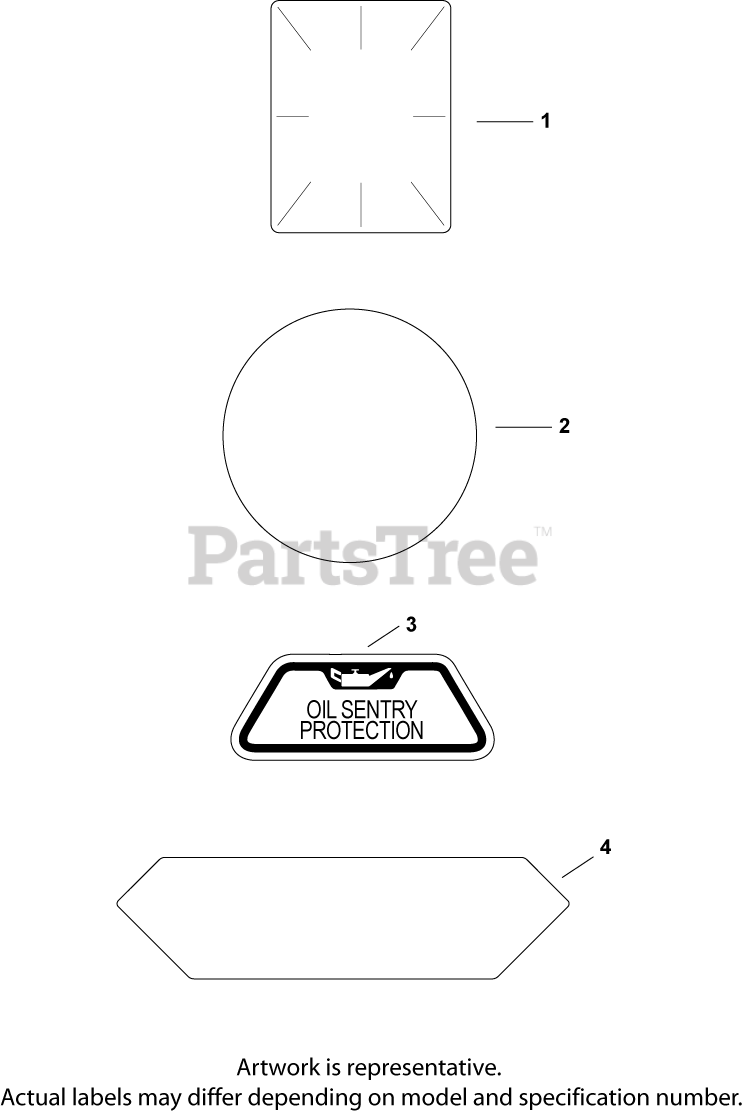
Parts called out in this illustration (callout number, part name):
1	DECAL, CLEAR LAMINATE USE 25 113 70-S
2	LABEL, (ROUND KOHLER GOLD)-USE 24 113 18
3	DECAL, OIL SENTRY - (#DSC)
4	DECAL, OIL COOLER - (#DSC)
